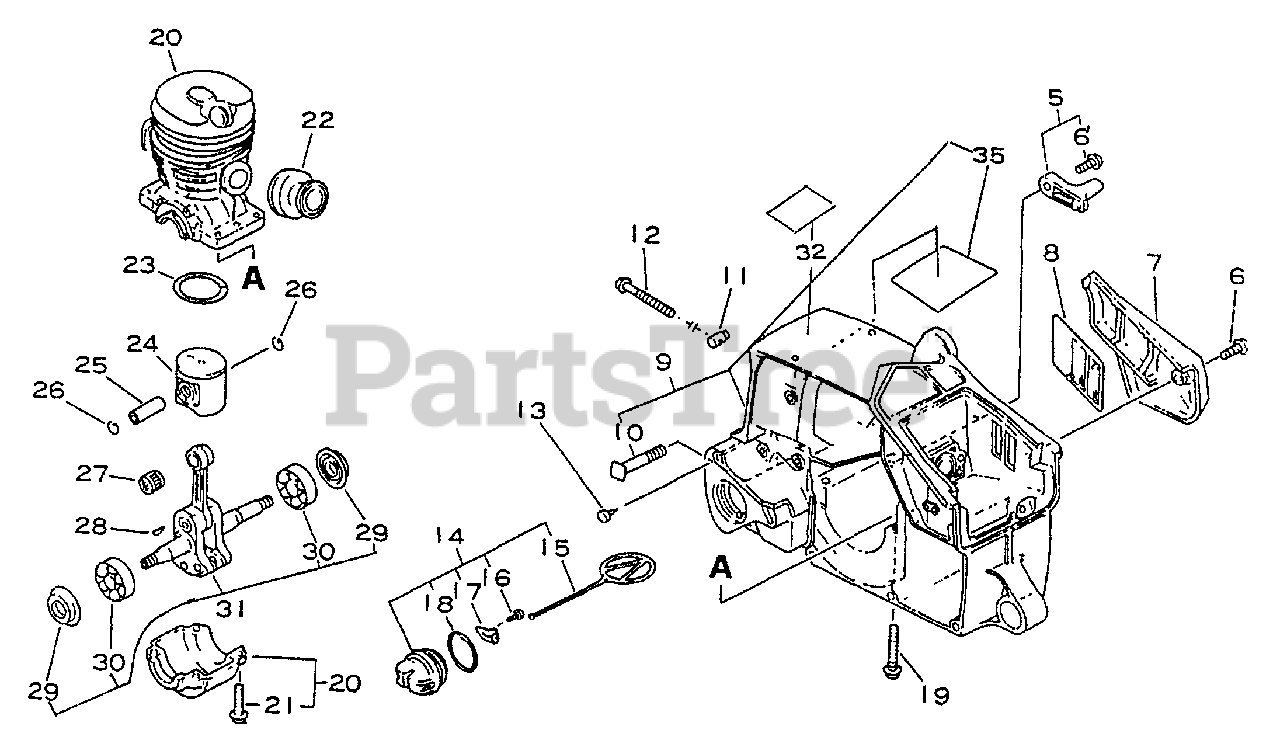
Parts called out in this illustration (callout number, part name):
5	CHAIN TENSIONER ASSY
6	SCREW 5×20
7	COVER, DUST
8	COVER
9	COVER, ENGINE
10	STUD, GUIDE BAR 8
11	TENSIONER, CHAIN
12	SCREW, TENSIONER
13	VENT ASSY
14	CAP ASSY
15	CONNECTOR, CAP L= 60 MM
16	SCREW, TAPPING 3×8
17	RETAINER, CONNECTOR
19	BOLT 5×30
20	CYLINDER ASSY
21	BOLT 5×25
22	BELLOWS, INTAKE
23	RING, PISTON
24	PISTON
25	PIN, PISTON
26	RING, RETAINING
27	BEARING, NEEDLE 9
28	KEY, WOODRUFF
29	SEAL, OIL
30	BEARING, BALL - 6201 C3
31	CRANKSHAFT ASSY
32	LABEL - BAR & CHAIN
35	SHIELD, HEAT
